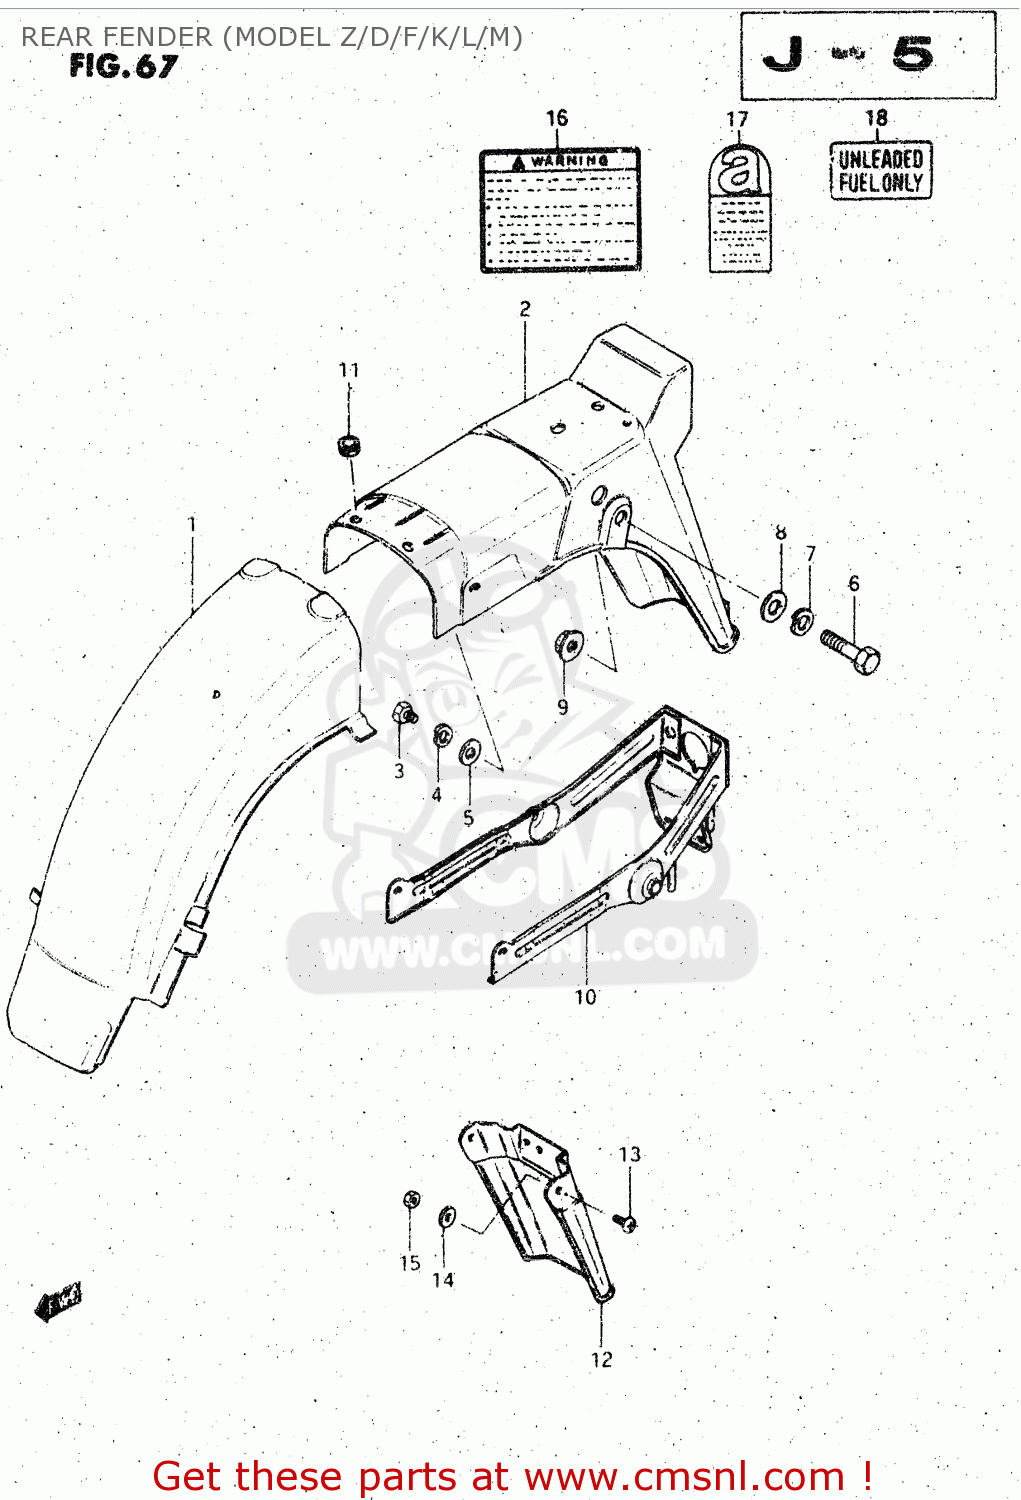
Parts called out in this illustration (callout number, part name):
1	BODY,FR
2	FENDER, REAR
3	BOLT
4	WASHER,LOCK
5	WASHER
6	BOLT 8X55
7	WASHER,LOCK,8.
8	WASHER
9	NUT
10	REINFORCEMENT,RR FENDER
11	CUSHION
12	EXTENSION, REAR
13	SCREW
14	WASHER 4MM
15	NUT
16	LABEL, WARNING SAFETY
17	LABEL,ASBESTOS WARNING
18	LABEL,FUEL CAUTION
19	MANUAL, OWNER'S
